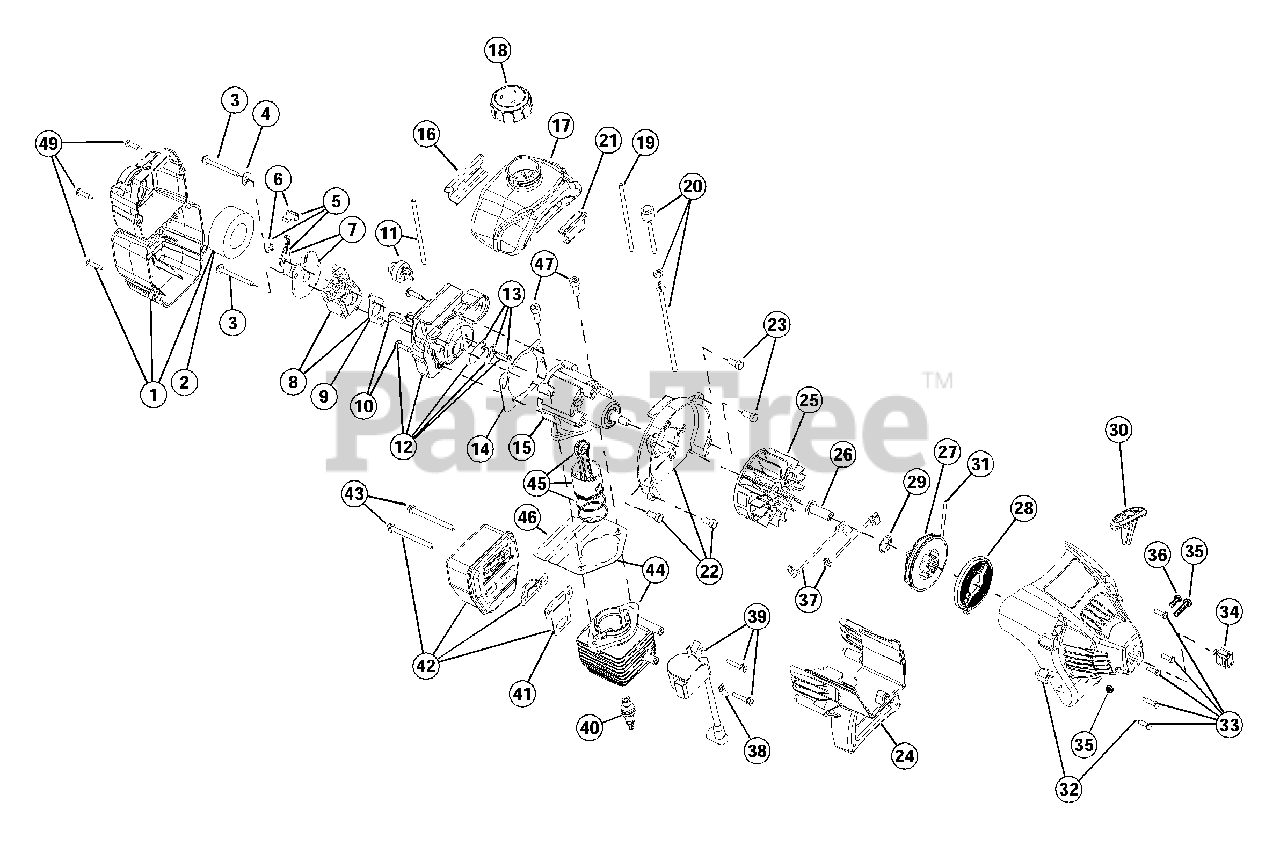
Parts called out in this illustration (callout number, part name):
1	Air Cleaner/Muffler Cover Assembly
2	Air Cleaner Filter
3	Carburetor Mounting Screws
4	Wavey Washer
5	Choke Lever Assembly
6	Choke Knob and Screw
7	Choke Lever and Plate
8	Carburetor Assembly
9	Carburetor Gasket
10	Carb Mount Screw
11	Primer and Hose Assembly
12	Carb Mount Assembly
13	Reed Assembly
14	Carburetor Mount Gasket
15	Crank Case Service Assembly
16	Rear Mounting Pad
17	Fuel Tank Assembly
18	Fuel Cap Assembly
19	Fuel Return Line
20	Fuel Line Assembly
21	Front Mounting Pad
22	Shroud Assembly
23	Shroud Screw
24	Shroud Extension and Stand
25	Flywheel Assembly
27	Recoil Pulley
28	Recoil Spring
29	Pulley Retainer
30	Pull Handle
32	Starter Housing Assembly
33	Housing Screws
34	On/Off Switch
35	Clamping Screw & Nut
36	Anti-Rotation Screw
37	Wire Leads
38	Ground Tab
39	Module Assembly
40	Spark Plug
41	Exhaust Gasket
42	Muffler Assembly
43	Muffler Mounting Bolt
44	Cylinder Assembly
45	Piston and Rod Assembly w/Rings
46	Cylinder Gasket
47	Cylinder Bolt
48	Spark Arrestor Screen
49	Cover Screws
